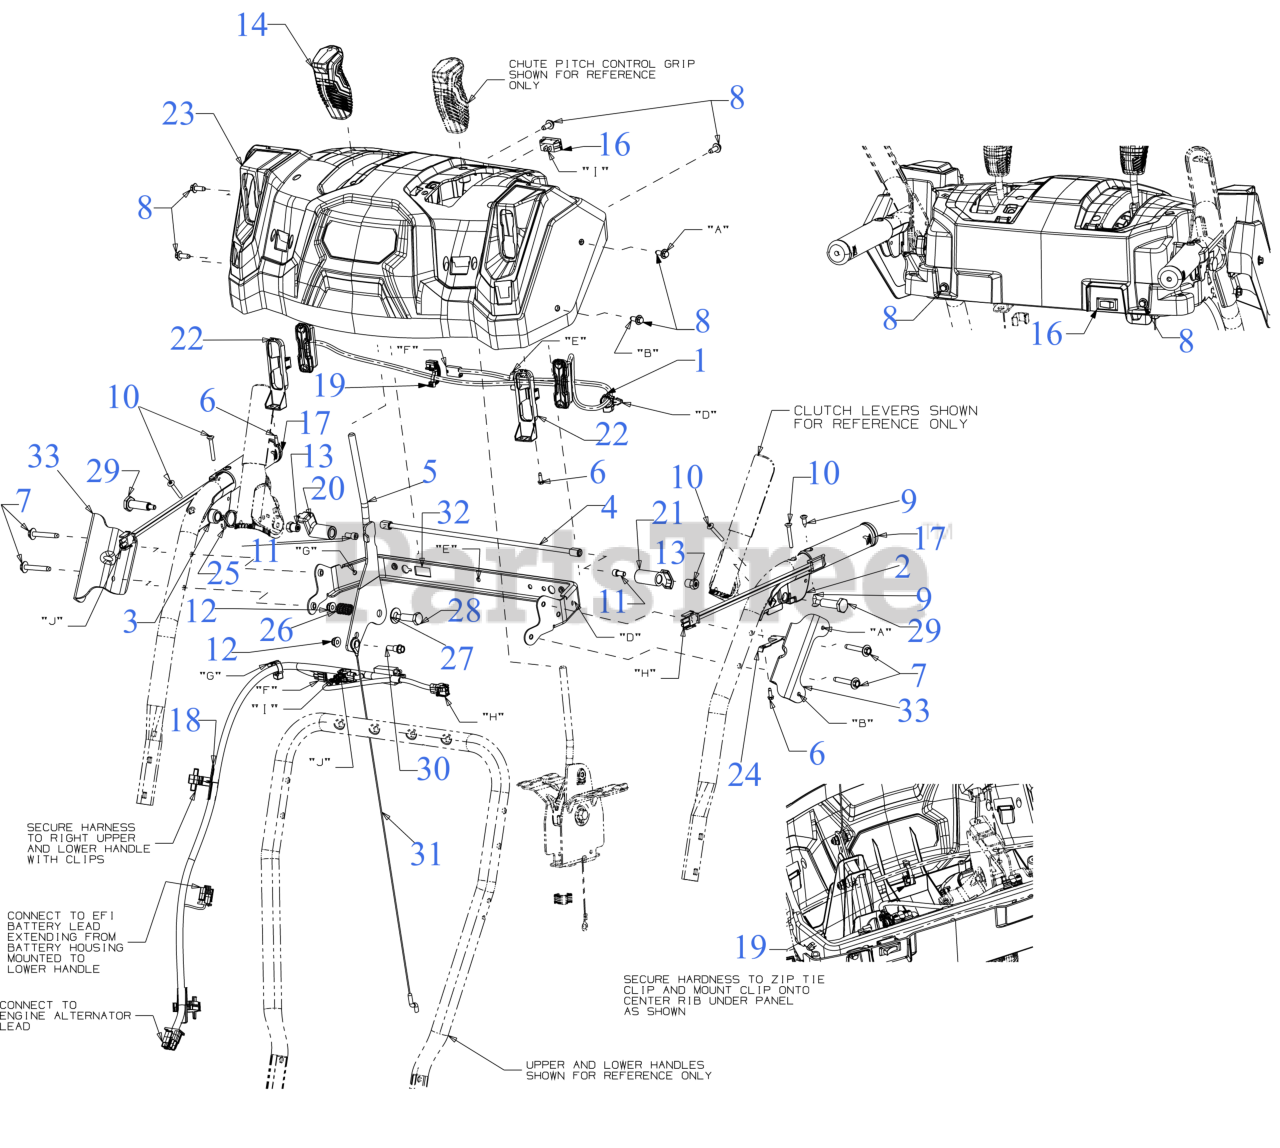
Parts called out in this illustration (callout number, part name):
1	HEADLIGHT HARNESS (W/LED)
2	CLUTCH LOCK HANDLE ASSEMBLY (LH)
2	HEX NUT
3	CLUTCH LOCK HANDLE ASSEMBLY (RH)
3	HEX NUT
4	PIVOT ROD
6	SCREW #8-16 x .50
7	SCREW 1/4-20 x 1.625
8	SCREW M6-1 x .625
9	SCREW-AB #12-24 x .625
10	SCREW #10-24 x 1.375
11	SCREW 1/4-20 x .50
12	FLANGE LOCK NUT
13	HEX NUT W/PATCH
16	HEATED GRIP SWITCH
17	HEATED GRIP
18	HARNESS (2S-2HDLT/HG/EFI/EGOV)
19	EDGE MOUNT ZIP TIE CLIP
20	LOCK PLATE
21	CLUTCH LOCK CAM
22	LENS BEZEL
23	HEADLIGHT PANEL
24	CLUTCH SPRING
25	TORSION SPRING
26	COMPRESSION SPRING
27	FLAT WASHER .38X.88
27	FLAT WASHER .401X.88
28	SHOULDER SCREW
29	SHOULDER SCREW .437 x 1.345 1/4-20
30	SHOULDER SCREW .342X.335X1/4-20
31	SELECTION CABLE
